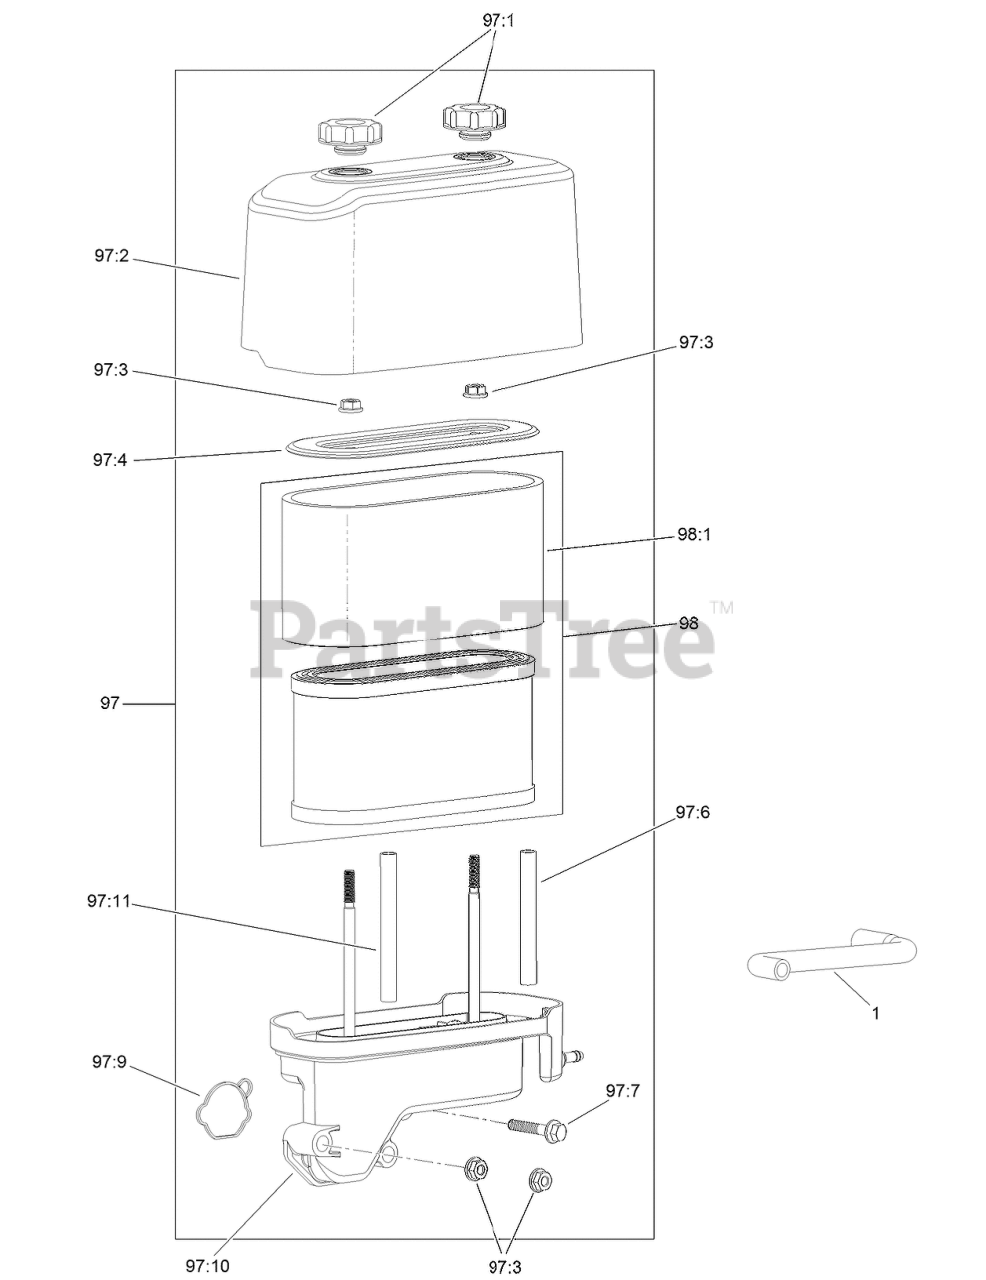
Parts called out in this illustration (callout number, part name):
1	TUBE-BREATHER
97:1	NUT-SPEED
97:2	COVER-FILTER, AIR
97:3	NUT-FLANGE
97:6	SPACER-FILTER, AIR
97:7	SCREW-HHF
97:9	GASKET-CARBURETOR
97:11	SPACER-FILTER, AIR
98:1	PREFILTER
